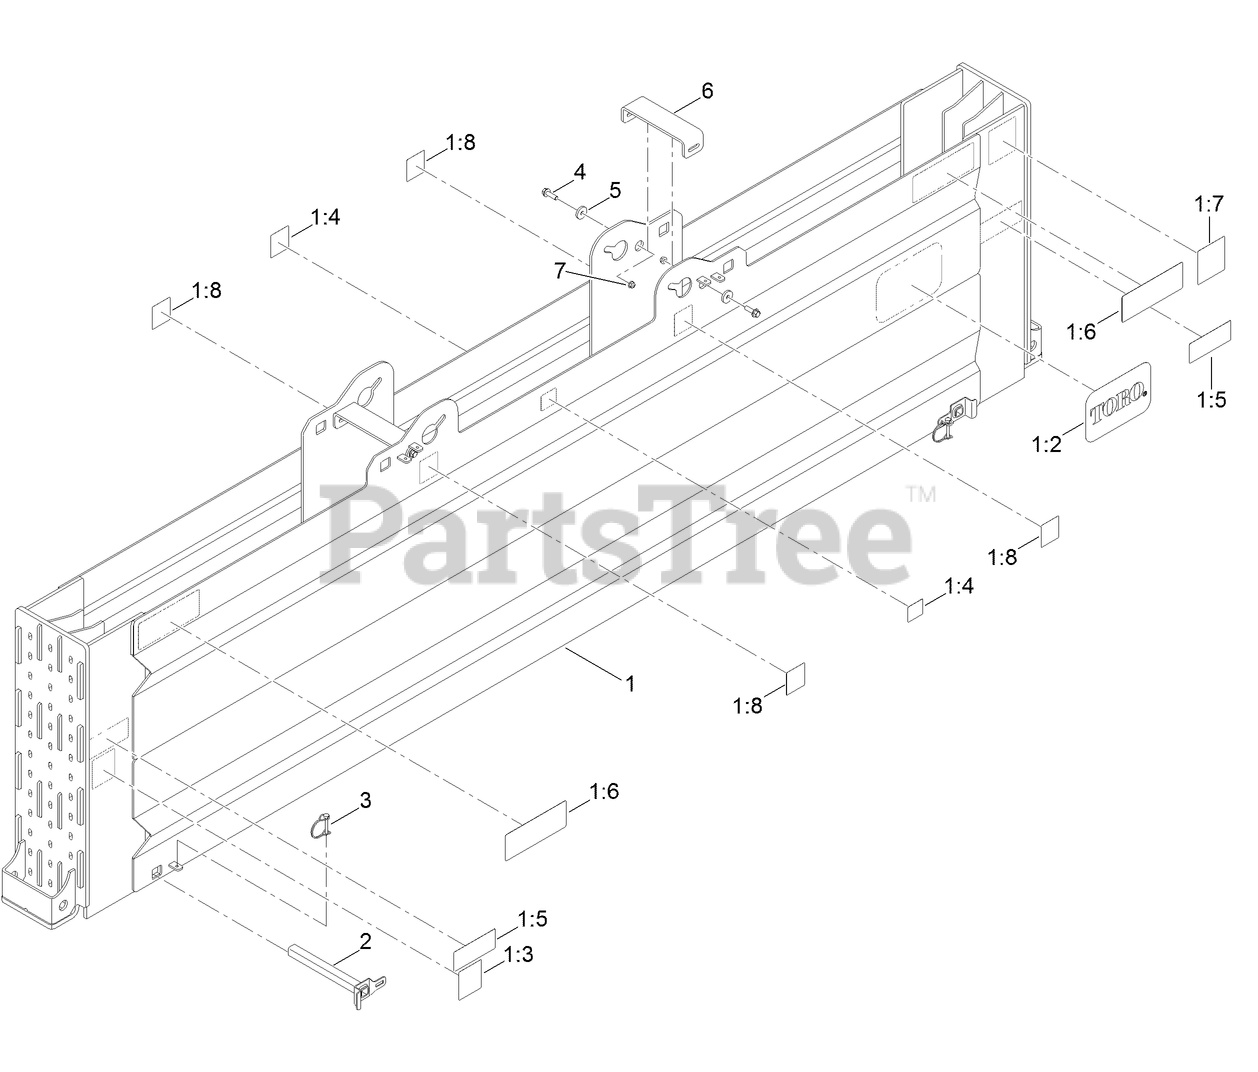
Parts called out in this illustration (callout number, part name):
1	ROD BOX ASM
1:2	DECAL
1:3	DECAL-WARNING, CRUSHING
1:4	DECAL-WEIGHT, ROD BASKET
1:5	DECAL-WARNING, HYDRAULIC PRESSURE
1:6	DECAL-DANGER, HAZARDOUS AREA
1:7	DECAL-DANGER, SHOCK
1:8	DECAL-LIFT HERE
2	PIN-ROD
3	PIN-HITCH
4	SCREW-HHF
5	SPACER
6	PLATE-GUARD, PIPE
7	NUT-HF, NI
